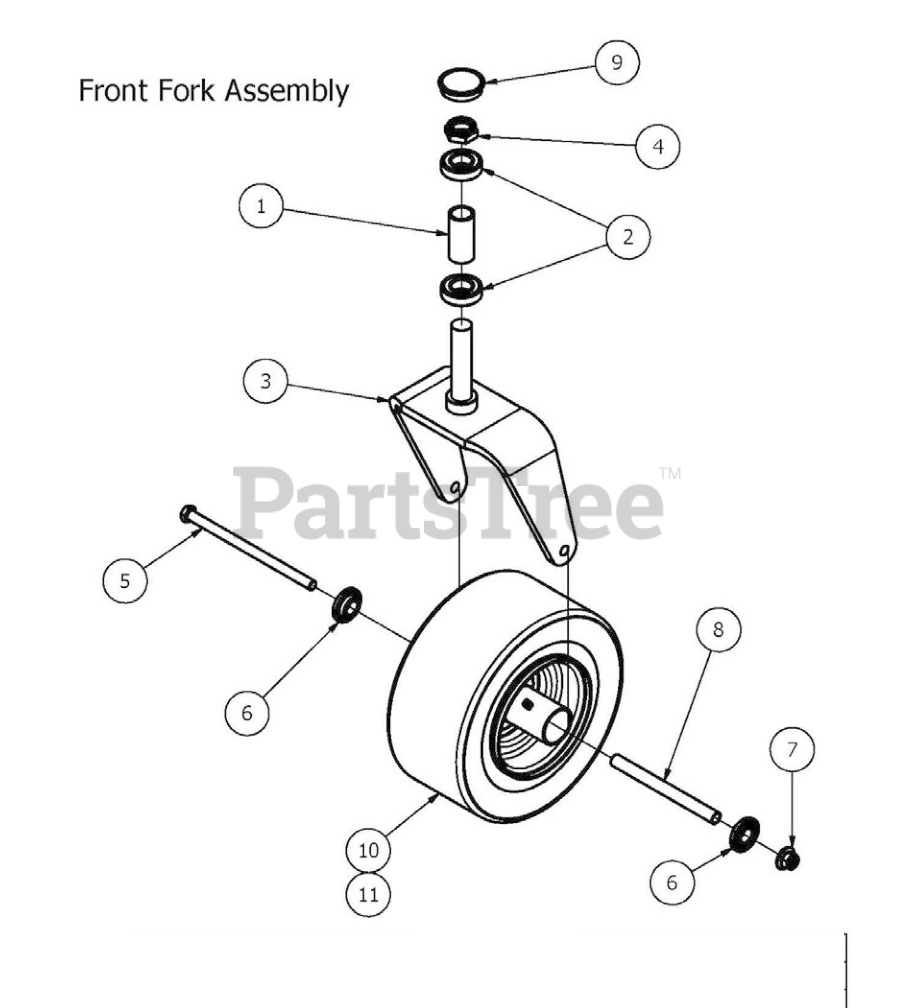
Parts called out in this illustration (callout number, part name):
1	2016 Front Bearing Spacer
2	Caster Bearing 2016 - 1641 Bearing
3	Front Fork
4	1" Fine Thread 1/2 Nylock Nut
5	1/2" x 9" GR 5 Hex Bolt
6	1 3/8" Wheel Bearing
7	1/2-13 Nylon Flange Nut
8	Front Wheel Spanner
9	2017 Bearing Cover
10	Tire and Wheel Assembly
11	Tire Only 13 x 6.50 -6
